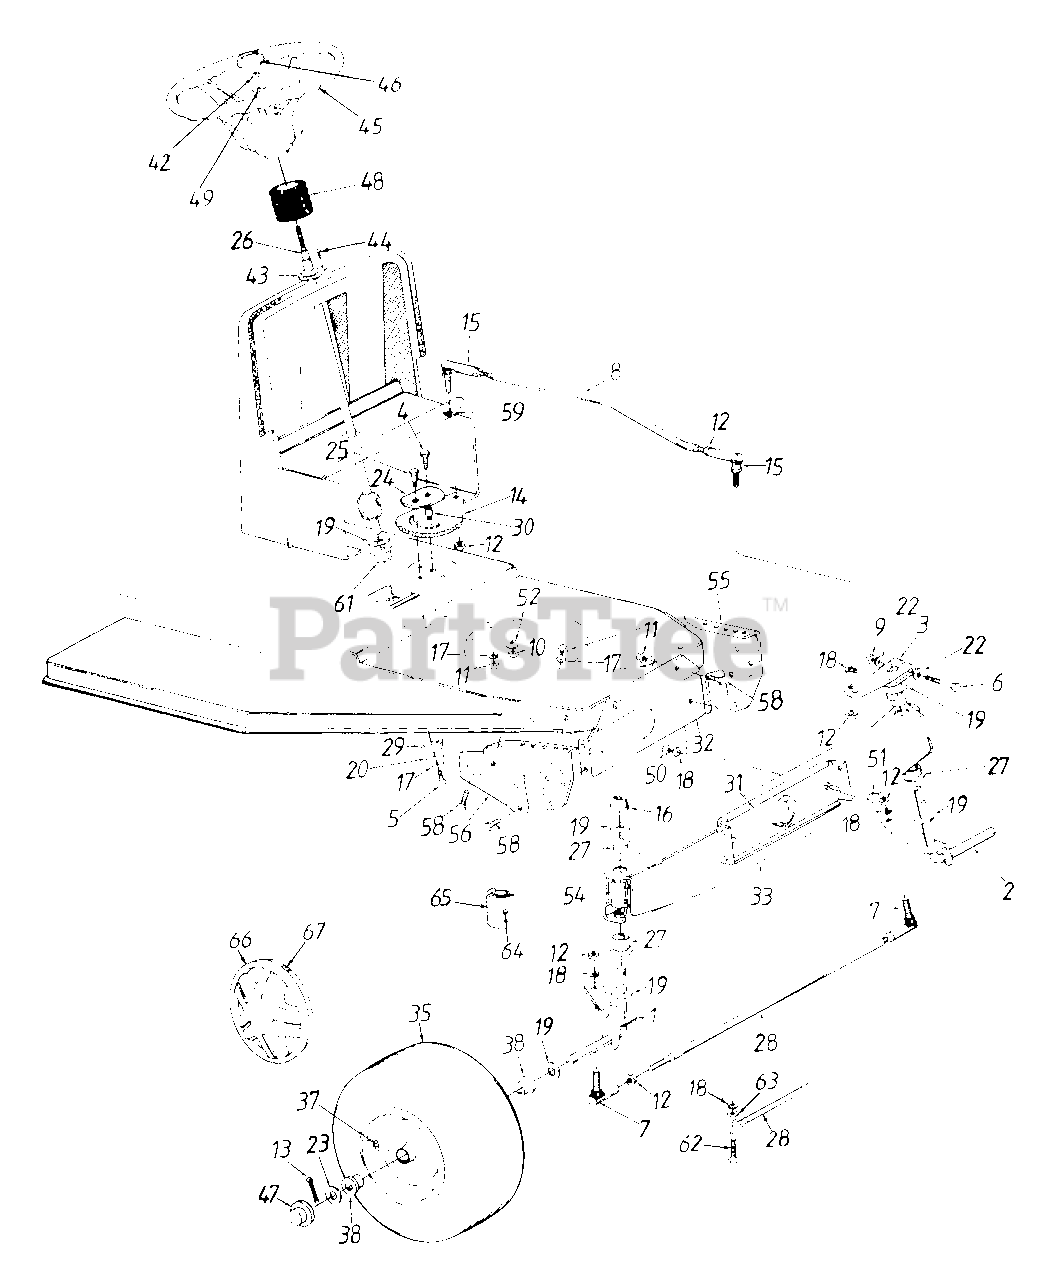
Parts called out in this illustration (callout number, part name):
1	Front Axle Ass'y. - R.H.
2	Front Axle Ass'y. - L.H.
3	Steering Arm
4	Hex Bolt 3/8-24 x 1" Lg.
5	Hex Bolt 5/16-18 x .62" (Spec)
6	Hex Bolt 5/16-24 x 2" Lg.
7	Ball Joint 3/8-24 Thd.
8	Steering Drag Link
9	Hex L-Nut 5/16-24 Thd.
10	Hex Nut 3/8-24 Thd.
11	Hex Nut 5/16-18 Thd.
12	Hex Jam Nut, 3/8-24 Thd.
13	Cotter Pin 1/8 Dia.
14	Steering Gear Segment
15	Drag Link Ball Joint 3/8-24 Thd.
16	Push Cap
17	L-Wash. 5/16" I.D.
18	L-Wash. 3/8" I.D.
19	Fl-Wash. .64" I.D. x 1.24"
20	Fl-Wash. .340" I.D. x 1.125"
22	Spr. Wash. .32" I.D. x .62"
23	Fl-Wash. .635" I.D. x 1.585"
24	Retainer Plate
25	Shld. Bolt .437" Dia. x .350"
26	Steering Shaft
27	Hex Flange Brg. .632" I.D.
28	Tie Rod
29	Spacer .985" I D.
30	Spacer .380" I.D.
37	Air Valve 15" x 6" w/Ball Bearing
38	Bearing 15" x 6" w/Plastic Bearing
38	Bearing 15" x 6" w/Ball Bearing
42	Hex L-Nut 5/16-24 Thd.
43	Steering Column Brg.
44	Cr-Sunk Scr. #10 x 5/8" Lg.
45	Steering Wheel (3 Spoke)
46	Steering Wheel Cap (Round)
47	Hub Cap
48	Bellow Steering Column
49	Bell-Wash .345" I.D. x .88"
50	Hex Nut 3/8-16 Thd.
51	Shld. Bolt 1/2" Dia. x 2.04"
52	Bell-Wash. .39" x 1.38" O.D.
54	Plastic Tube
55	Pivot Bar Side Plate - L.H.
56	Pivot Bar Side Plate - R.H.
58	Hex Wash Tap Scr. 5/16-18 x .62" Lg.
59	L-Wash. 3/8" I.D. (H.D.)
61	Hex Flange Brg. .634" Dia.
62	Hex Bolt 3/8-24 x 1.5" Lg.
63	Hex Jam Nut 3/8-24 Thd.
64	Grease Fitting
65	Pivot Bar End Cap
66	Spring Clip
67	Hub Cap (Beige)
67	Hub Cap (Gray)
